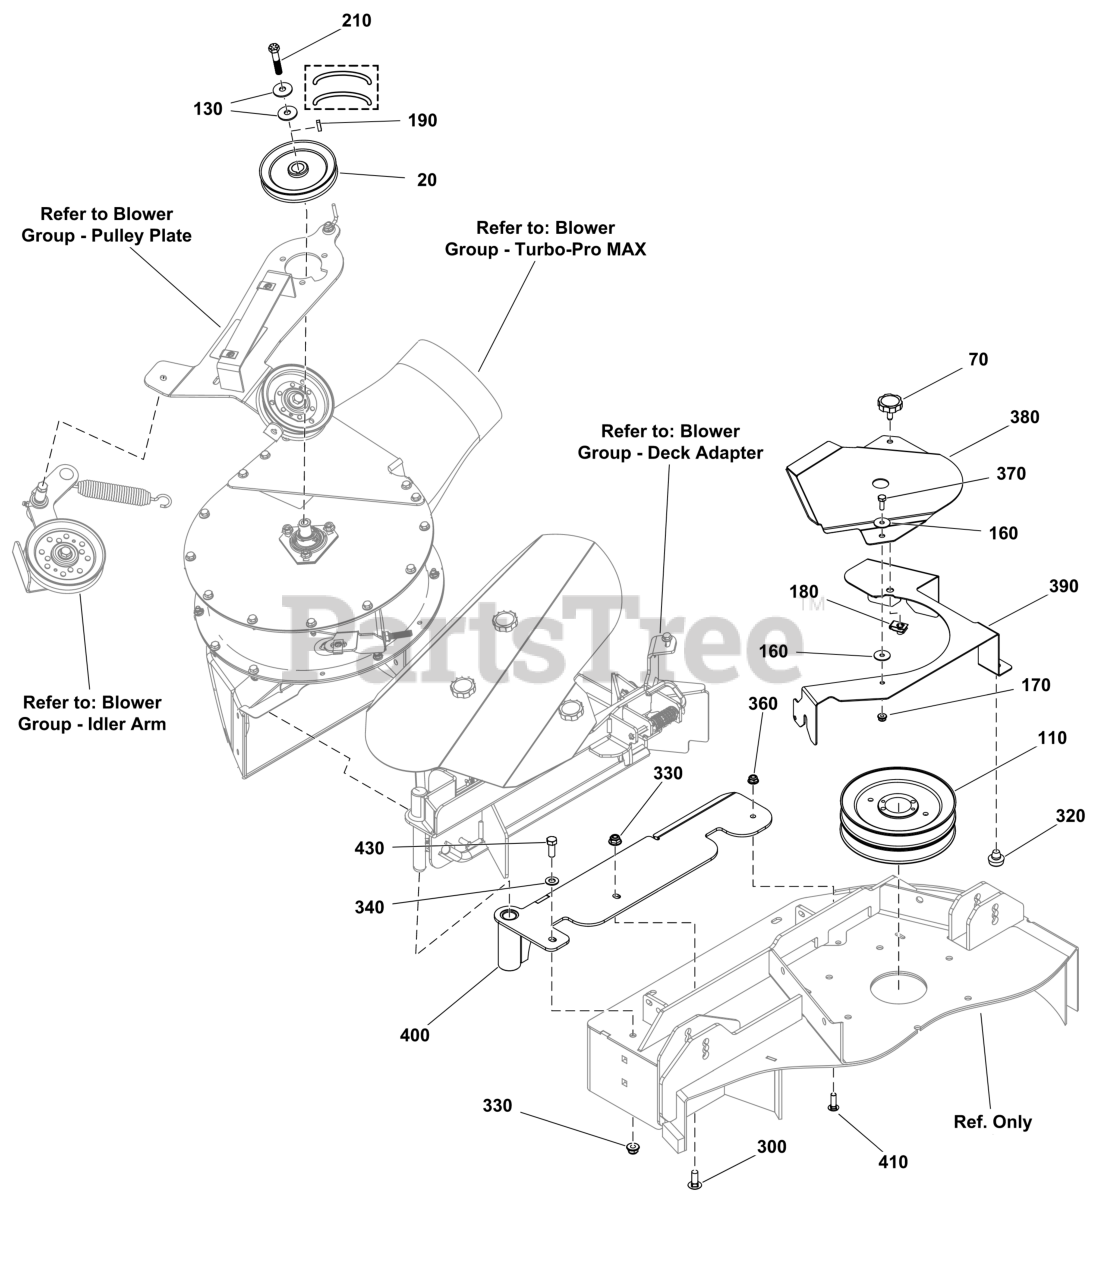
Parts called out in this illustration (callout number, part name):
70	KNOB, 5/616-18 X 1
130	WASHER, BEVELED
160	WASHER, 1/4 FENDER
180	BODY CLIP, 5/16-18 X
190	KEY, SQUARE
210	BOLT
300	BOLT, RD HD, 3/8-16X1
320	MOUNT-VIBRATION
330	NUT, 3/8-16 HEX NYLOCK
360	NUT
370	BOLT, 1/4-20 X 3/4" G
380	SHIELD, BELT
390	GUARD, Pulley
410	BOLT, 5/16-18 X 1", C
430	BOLT, 3/8-16 X 1" GD5
